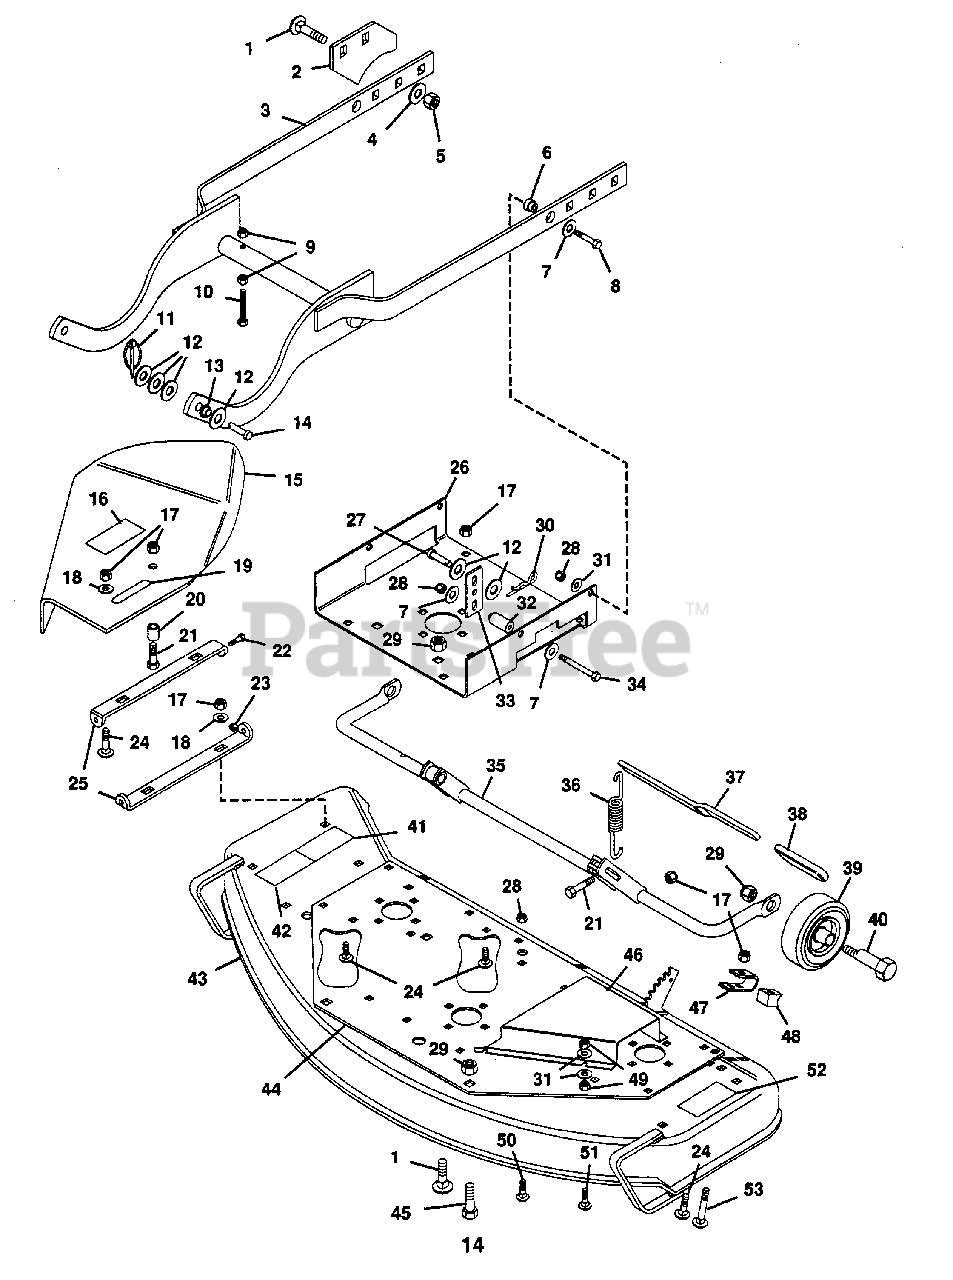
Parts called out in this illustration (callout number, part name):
1	Bolt, Carriage 1/2-13x1.25
2	Plate, Cam
3	Weldment, Drag Arm
4	Washer, Flat .531x1.250x.100
5	Nut, Lock 1/2-13
6	Bush., Flg. .344x1.00x.670 Stl.
7	Washer, Flat .375x1.125x.065
8	Bolt, Hex 5/16-18x1.375
9	Nut, Lock 5/16-18
10	Bolt, 5/16-18x2.50 All Thread
11	Pin, Klik
12	Washer, Flat .531x1.063x.095
13	Bush., Flg. .512x.750x.459 Ny.
14	Pin, Clevis .50x1.330
15	Shield, Safety Ext. 50" Mower
16	Decal, Caution
17	Nut, Lock 3/8-16
18	Washer, Flat .406x.812x.065
19	Decal, Width of Cut
20	Stop, Chute
21	Bolt, Hex 3/8-16x1.50
22	Bolt, Hex 1/4-20x.875
23	Nut, Lock 1/4-20
24	Bolt, 3/8-16x1 Rd Hd Sq Nk
25	Bracket, Chute
26	Channel
27	Pin, Clevis .50x.875
28	Nut, Lock 5/16-18
29	Nut, Lock 1/2-13
30	Pin, Cotter Hair
31	Washer, Flat .344x.688x.065
32	Bushing, Link
33	Link
34	Bolt, Hex 5/16-18x2.50
35	Weldment, Axle
36	Spring, 40 and 50 Inch Mower
37	Lever, Height of Cut
38	Grip, Handle
39	Wheel, Gauge
40	Bolt, Eccentric
41	Decal, Warning Eye
42	Decal, Danger Hand
43	Weldment, 50" Deck
44	Plate, Support
45	Bolt, Hex 1/2-13x1.00
46	Cover, Belt L.H.
46	Cover, Belt R.H.
47	Bracket, Axle Support
48	Stop, Nylon
49	Nut, Jam 5/16-18 Hex
50	Bolt, Carriage 5/16-18x.75
51	Bolt, Carriage 5/16-18x1.00
52	Decal, Danger Foot
53	Bolt, 3/8-16x2 Rd Hd Sq Nk
